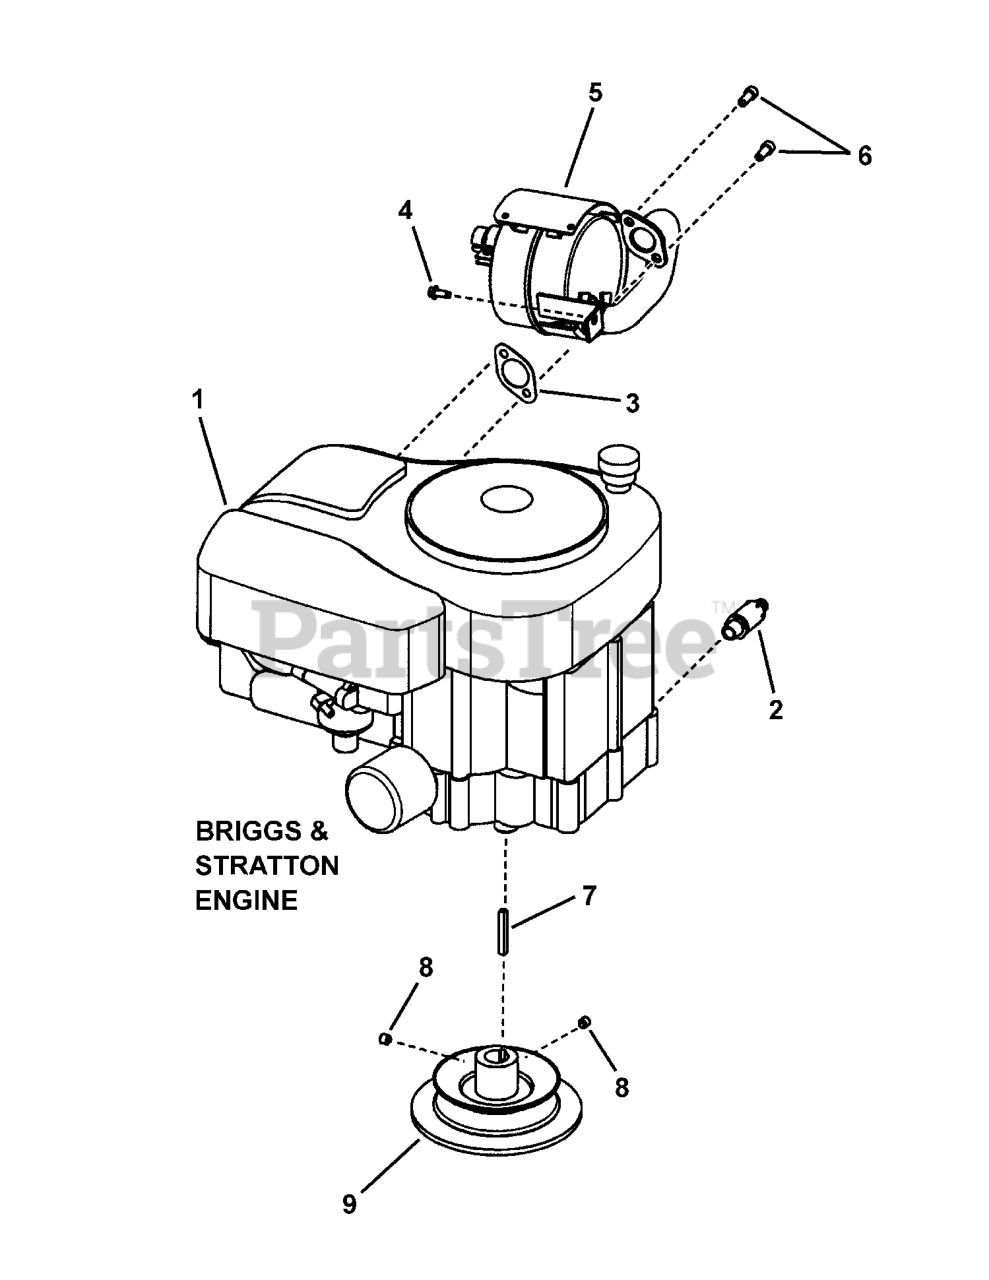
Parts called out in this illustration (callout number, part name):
1	* ENGINE, 12.5HP Briggs Intek OHV, E. S. No Recoil
2	ASSEMBLY, Oil Valve
3	GASKET, Exhaust
4	SCREW, 1/4-20 x 5/8" Hex Washer Head Self-Tap
5	MUFFLER, w/Heat Shield (Briggs 11 thru 17.5HP)
6	SET SCREW, 5/16-18 x 3/4" Socket Head, GR8
7	KEY, 1/4" Square x 2" Long
8	SET SCREW, HRSS, 3/8-16 x 3/8"
9	WELDMENT, 5.75" O.D. Drive Disc
